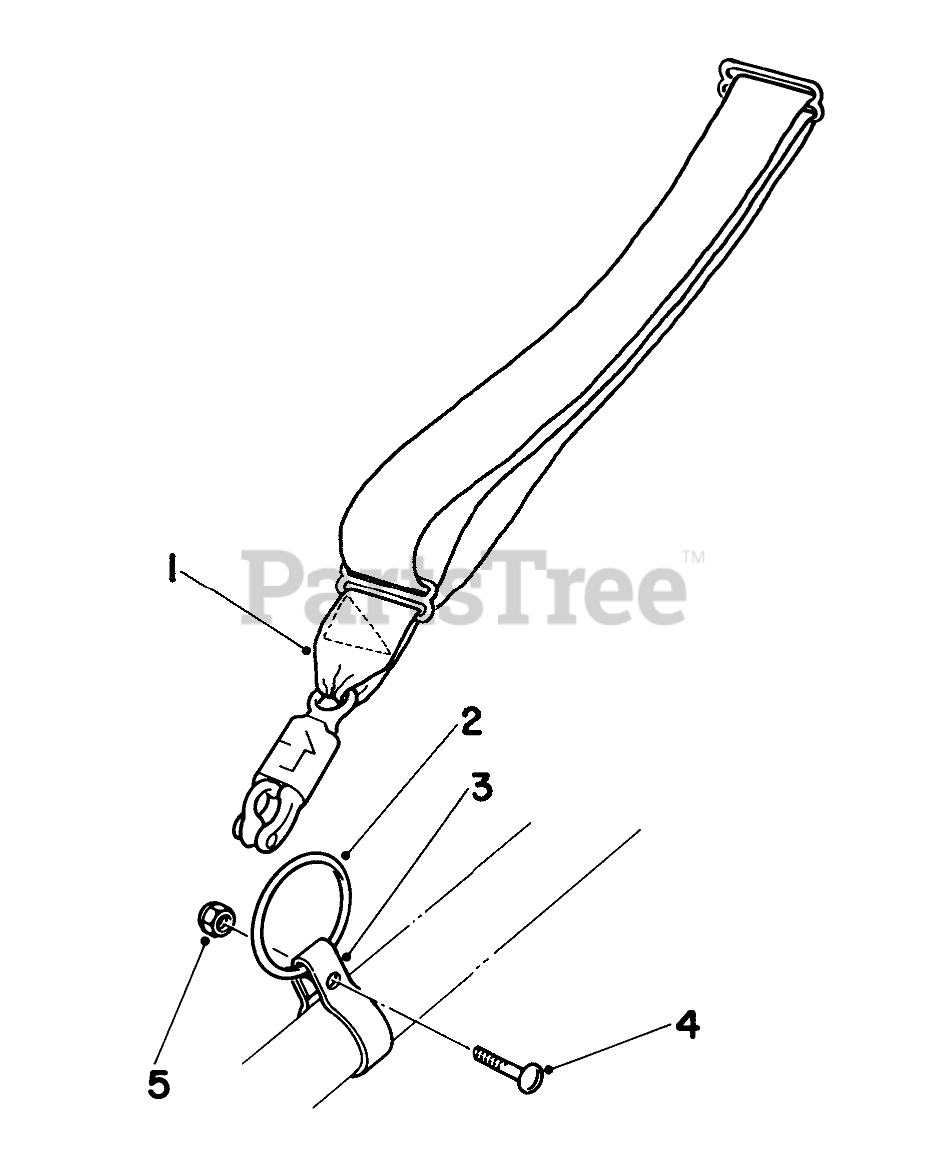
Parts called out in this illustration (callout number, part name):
1	Shoulder Strap
2	Ring
3	Clamp
4	SCREW-SRH
5	NUT-LOCK, NI
